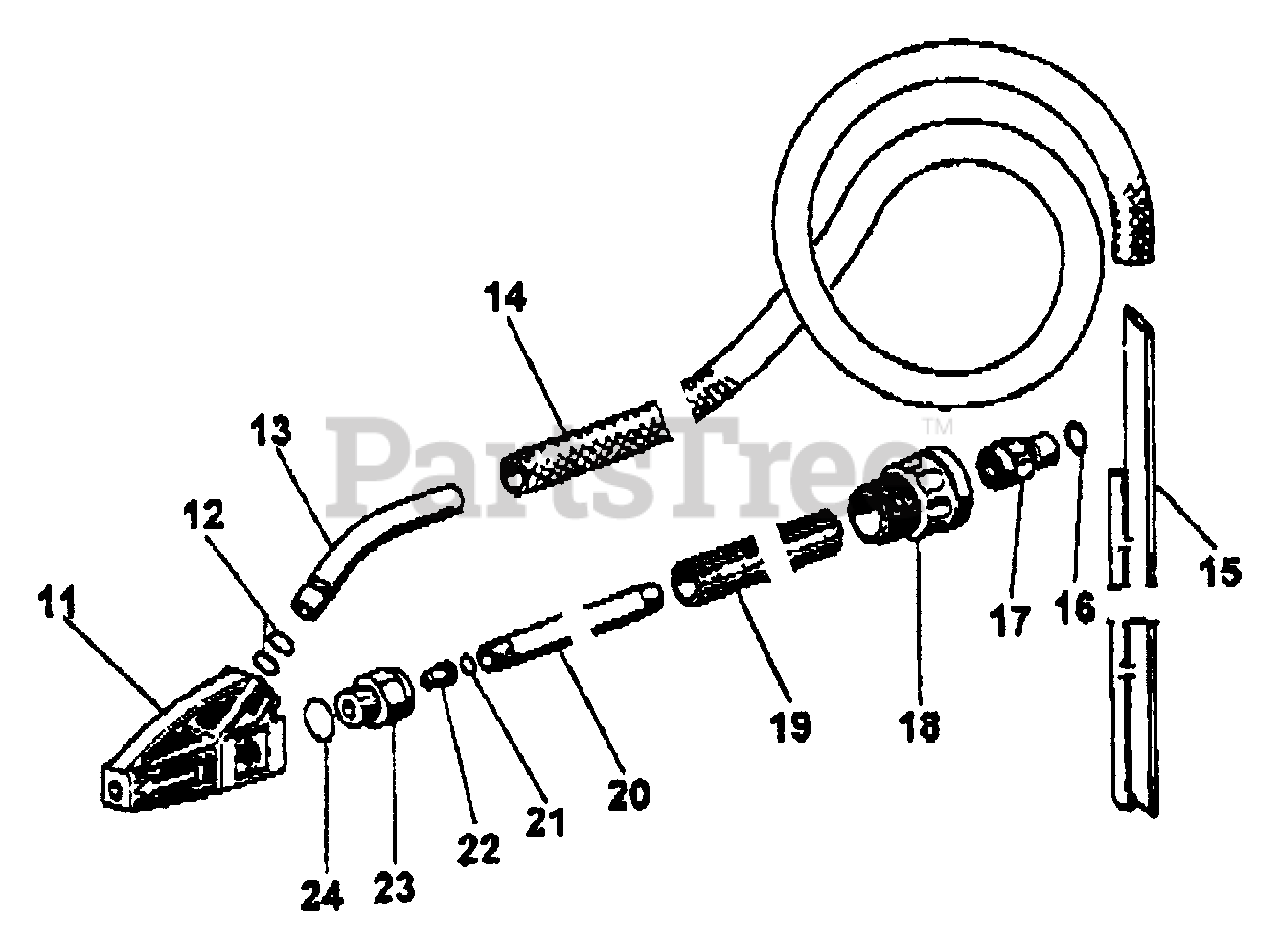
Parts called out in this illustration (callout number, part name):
11	NOZZLE, SAND
12	O-RING
13	CONNECTOR, SAND TUBE
14	TUBE, SAND
15	PROBE, SAND
16	O-RING - .359 X .103
17	COUPLING - MALE
18	RINGNUT
19	GRIP, HANDLE
20	TUBE
22	NOZZLE, SAND BLASTING
23	HOLDER, NOZZLE
24	O-RING - .614 X .070
